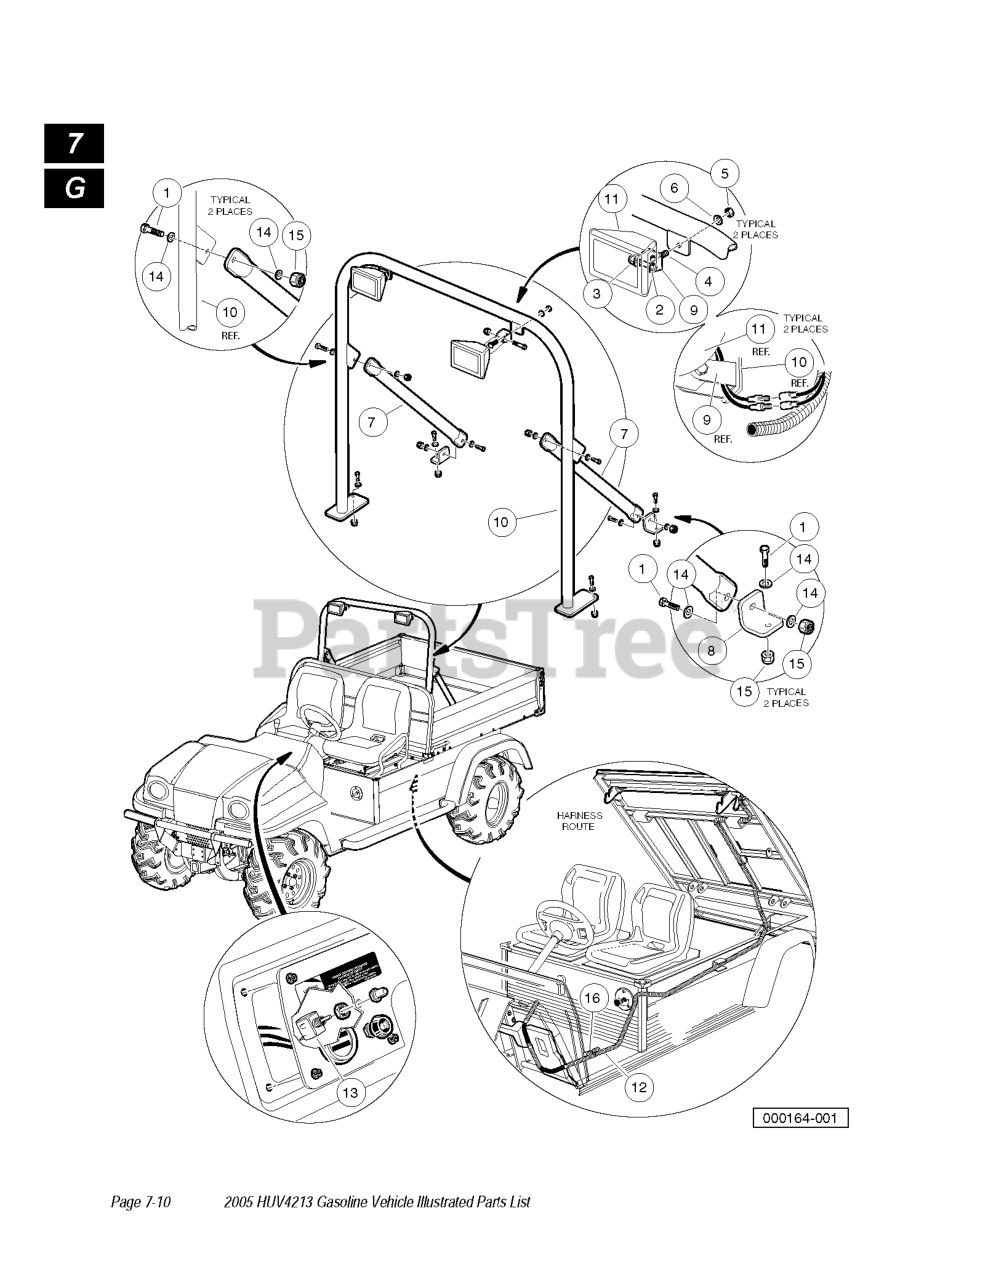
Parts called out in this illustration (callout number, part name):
1	SCREW HEX CAP
7	BRACE. LIGHT BAR
8	BRACKET, BRACE MTG
9	BRACKET, LIGHT MTG
11	LIGHT, LIGHT BAR
12	WIRE HARNESS, LIGHT BAR
14	WASHER, 5/16 TYPE A FLAT
15	LOCKNUT, 5/16-18 NYLON INSERT
16	TIE WRAP, 8" NYLON
17	37.5 Watt Light Bar Bulb
